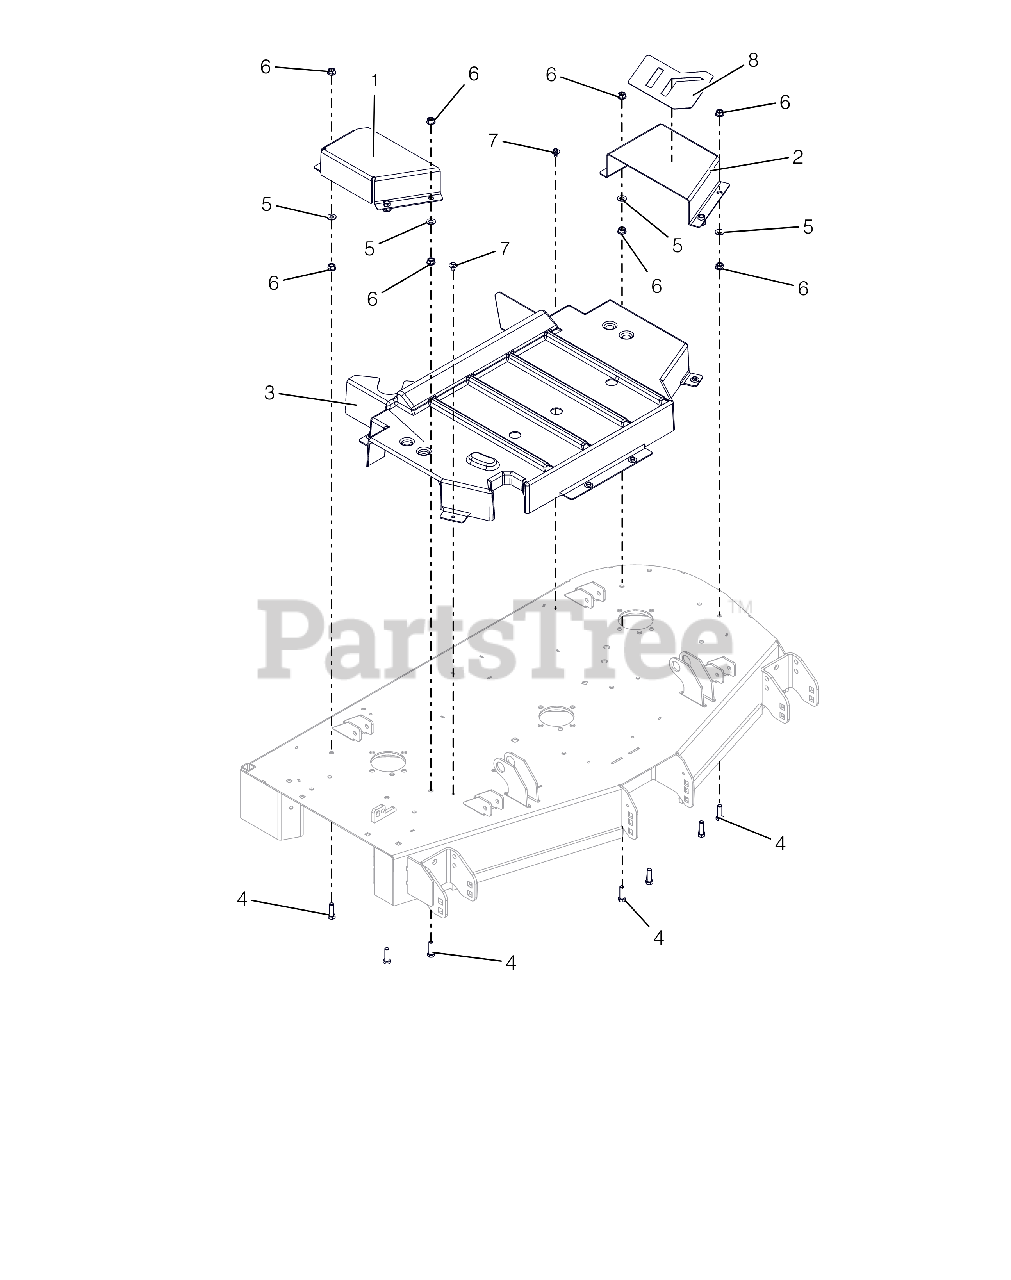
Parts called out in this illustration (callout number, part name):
1	GUARD BELT, 48" RIGHT CE
2	GUARD BELT 48" LEFT CE
3	GUARD, CENTER DECK SPINDLE CE
4	@BLT-HEX .38-16X1.25 GR5 YWZC
5	@WSHR-FL-STL.406X.812X.065 YWZ
6	@NUT-SPNLK-FLG .375-16 YWZC
7	SCR-TAP .25-20X.50 LGHWH TR YZ
8	GRIP TAPE 48 BELT COVER
